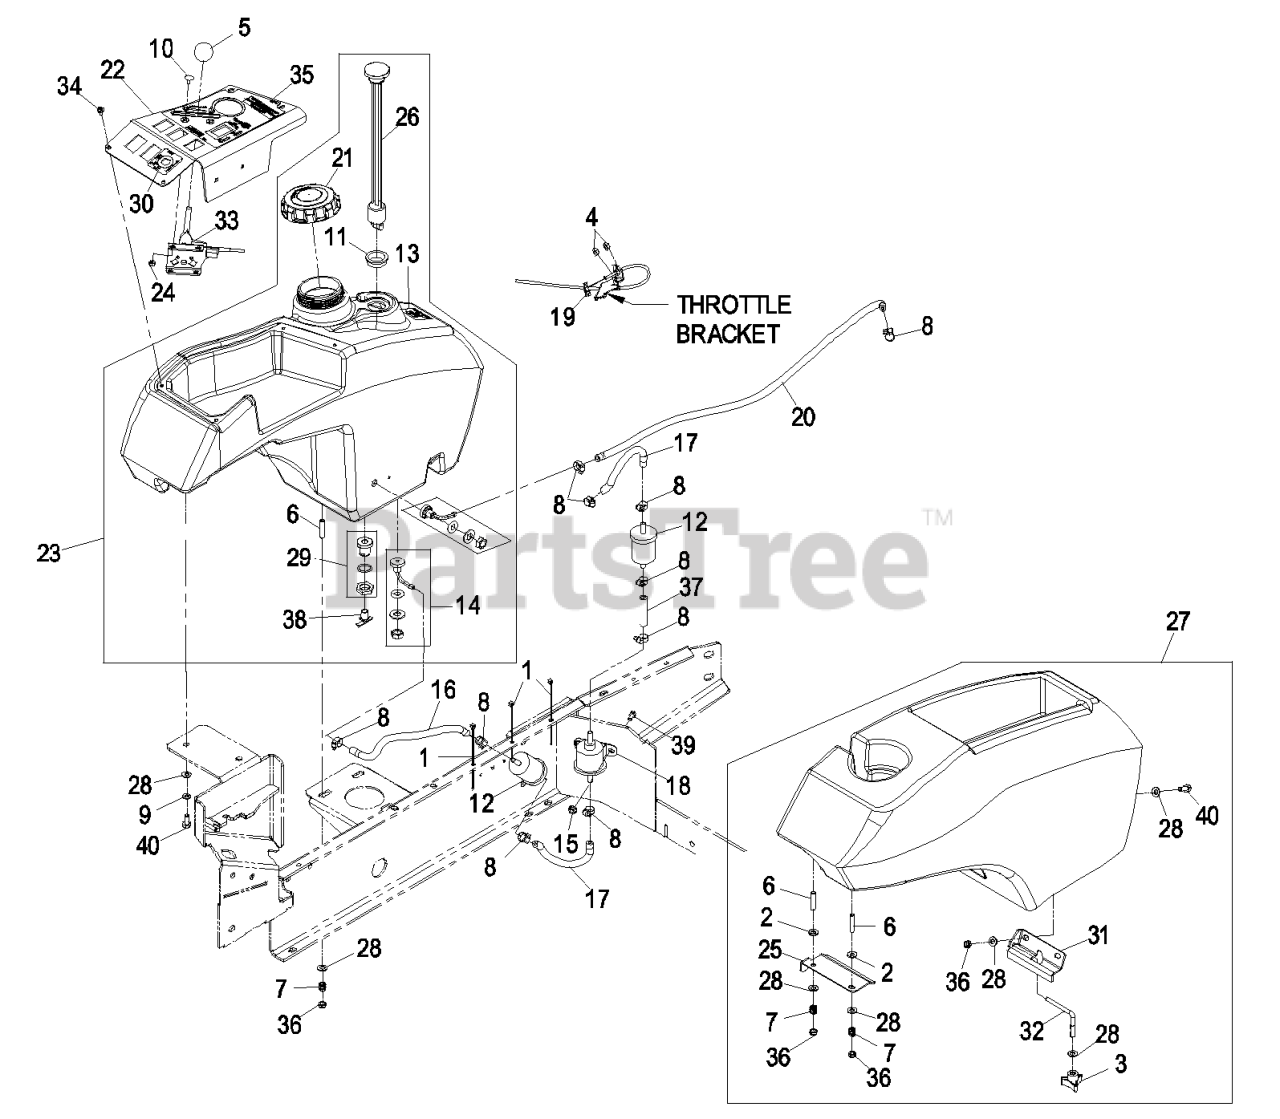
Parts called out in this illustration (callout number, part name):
1	TIE-CABLE
2	WASHER-SPRING
3	KNOB-3 PRONG
4	NUT-JAM
5	KNOB-BALL
6	STUD
7	SPRING-TANK, FUEL
8	CLAMP-WORM
9	WASHER-LOCK
10	BOLT-CARR
11	CONTACT ORDER SERVICES
12	FILTER-FUEL
13	DECAL-FUEL
14	CLUTCH KIT
16	HOSE-FUEL
17	HOSE-FUEL
19	SWIVEL-STOP, CABLE
20	HOSE-FUEL
21	CAP-FUEL, DIESEL
22	ASM,FMZ DIESEL CTRL PANEL
23	ASM,FUEL TANK FMZ DIESEL
24	NUT-LOCK, NI
25	HOOK,FENDER (PLATED)
26	Gauge, Fuel
27	ASM,FENDER FMZ
28	WASHER-PLAIN
29	Asm, Fitting 1/4" Npt
30	DECAL,IGNITION
31	BRACKET,FENDER
32	BOLT,FENDER
33	CABLE,THROTTLE
34	SCREW-PPH
35	DECAL,CONSOLE FMZ DIESEL
36	NUT-LOCK, NI
37	HOSE-FUEL
38	DRAINCOCK
39	SCREW-HH
40	SCREW-HH
